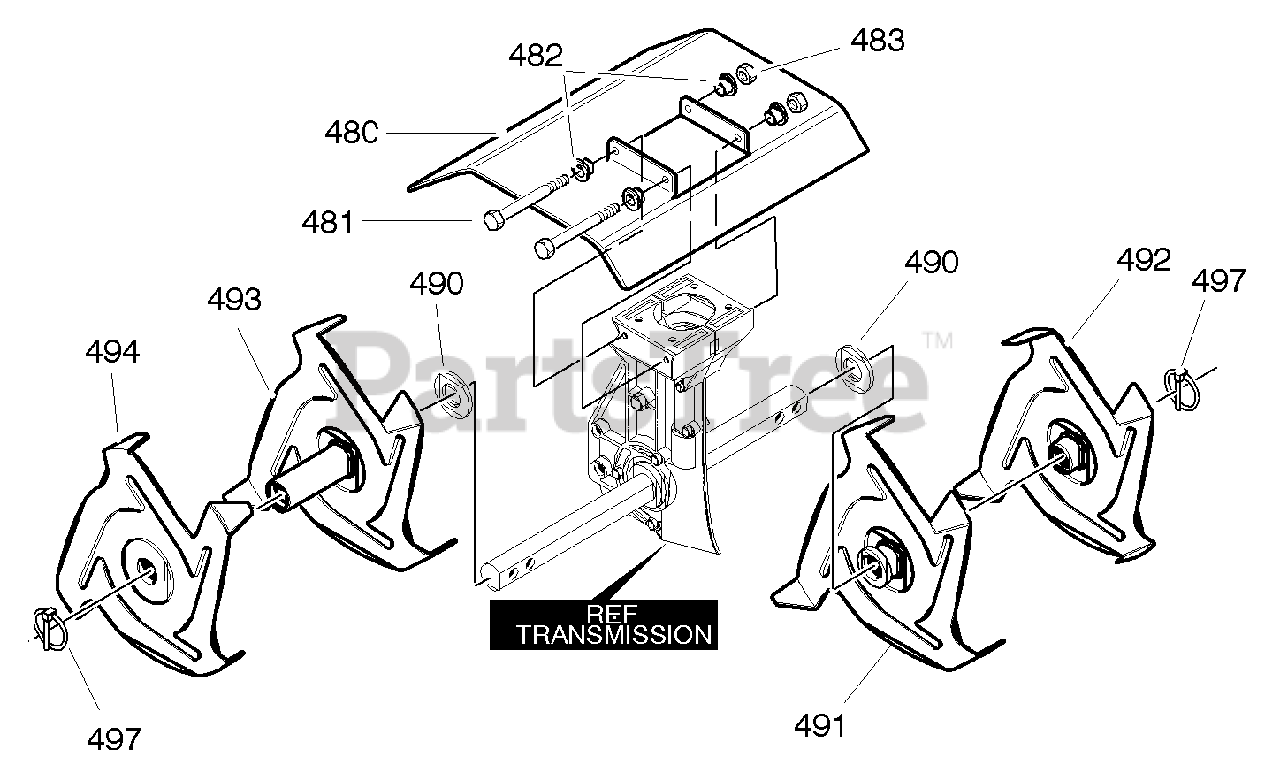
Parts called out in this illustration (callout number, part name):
480	Shield, Tine
481	Screw, 1/4-20x5.50
482	Spacer, Flange
483	Nut, 1/4-20
490	Washer, Felt
491	Tine Assy. Inner LH
492	Tine Assy. Outer LH
493	Tine Assy. Inner RH
494	Tine Assy. Outer RH
497	Pin, Latch
